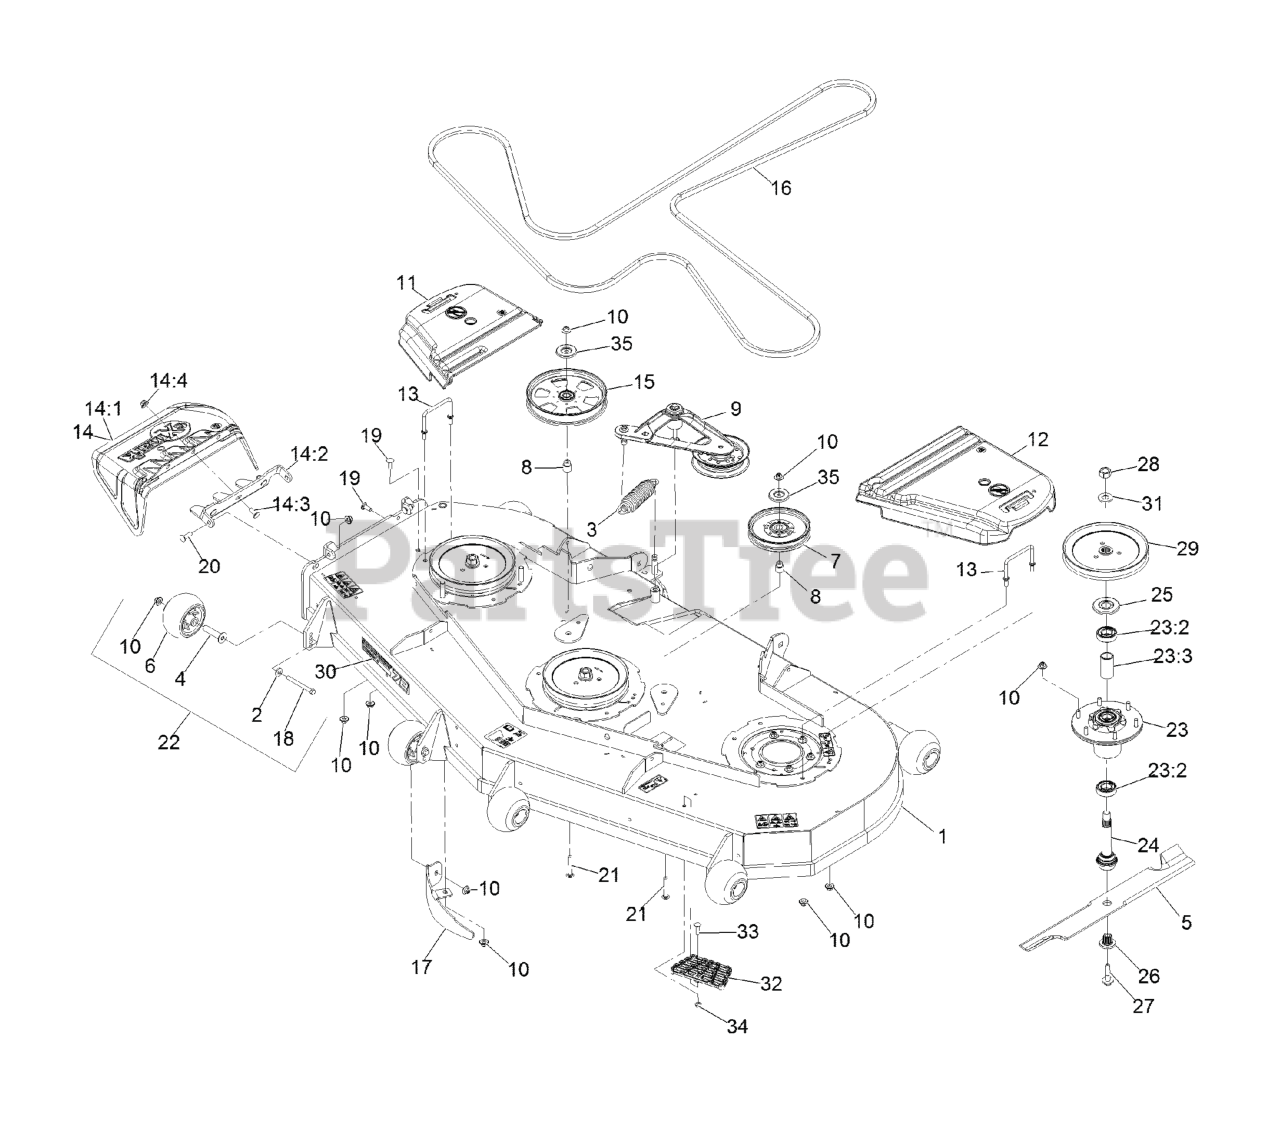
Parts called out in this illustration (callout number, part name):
1	ASM,DECK W/DECALS 724
2	WASHER-BELLEVILLE
3	SPRING-EXTENSION
4	AXLE, ROLLER
6	ROLLER-SCALP, ANTI
7	IDLER-PULLEY
8	BUSHING-IDLER
9	DECK IDLER ASM
10	Nut-Nyloc 3/8-16 Flg
11	COVER-BELT, RH
12	COVER-BELT, LH
13	WIREFORM-COVER
14	ASM,DISCHARGE CHUTE
14:1	CHUTE,DISCHARGE
14:2	BRACKET,DISCHARGE CHUTE
14:3	SCREW-CARR
14:4	Nut-Nyloc 3/8-16 Flg
15	PULLEY-IDLER, FLAT
17	BAFFLE-DOGLEG, LZ72
18	SCREW-HH 3/8-16 X 3 3/4 GR 8
19	SCREW-CARR
20	Bolt-Carriage 3/8-16 X 1 1/4
21	SCREW-CARR
22	KIT, ANTI-SCALP ROLLER
23	ASM-CUTTER HSG WITH BEARINGS
23:2	BEARING-BALL
23:3	SPACER-BEARING
24	ASM-SPINDLE AND SEAL
25	GUARD,BEARING TOP .989
26	BUSHING,SPLINED
27	SCREW,SEMS 1/2-20 X 2.19
28	NUT-HEX
29	SHEAVE,BLADE DRIVE 8.74
30	DECAL, 724
32	STEP-DECK
33	Bolt-Carriage 5/16-18 X 1 1/4
34	NUT-HF, NI
35	SHIELD-DUST
